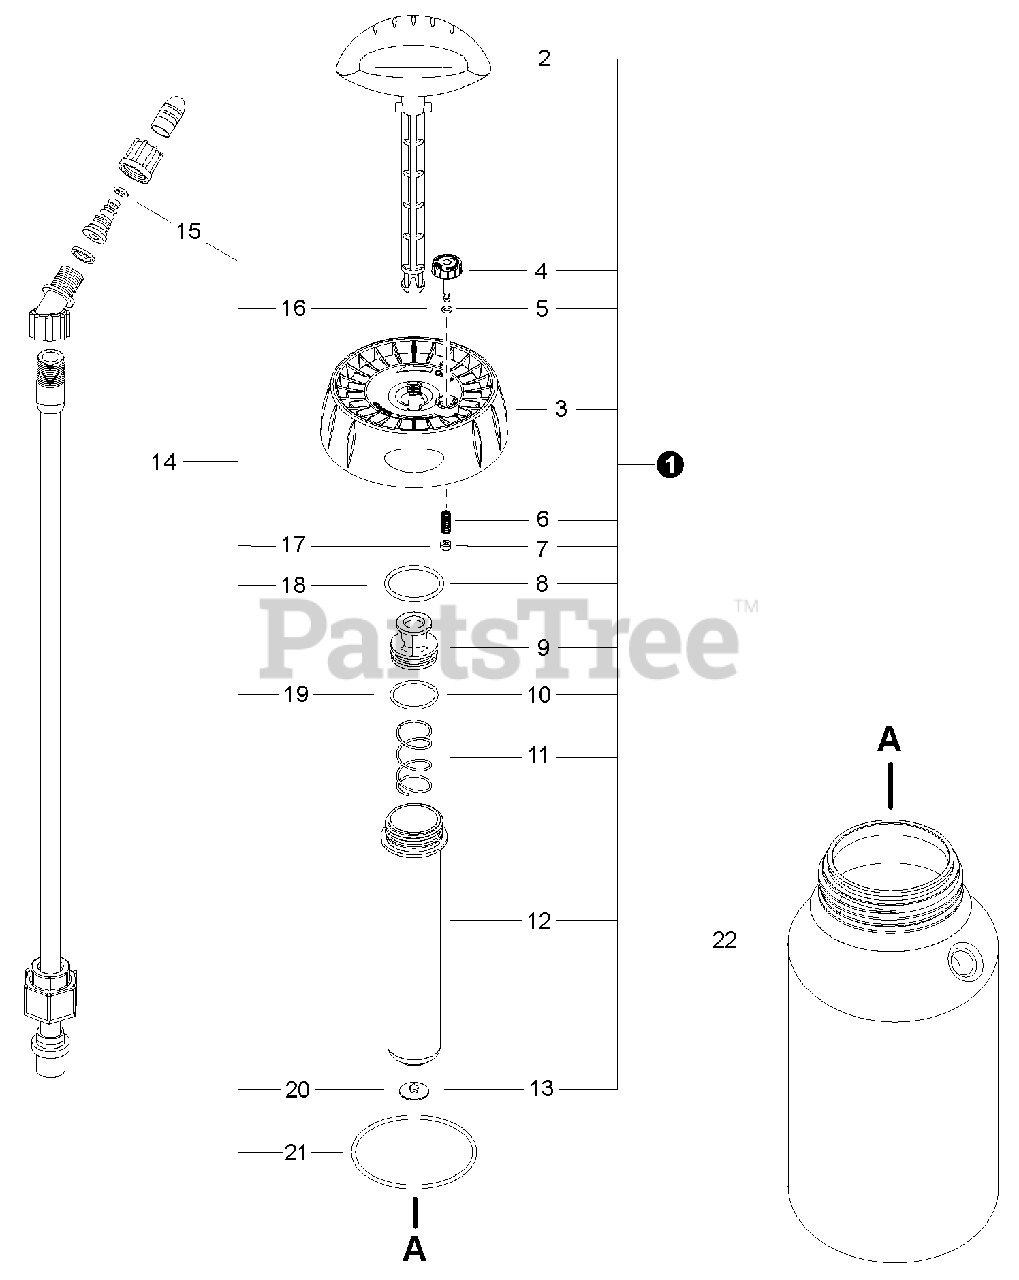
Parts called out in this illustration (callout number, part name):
1	PUMP ASSY
2	HANDLE, PUMP
3	CAP, TANK
4	CAP
5	O-RING, PRV
6	SPRING, PRV
7	RING, RETAINING - PRV
8	O-RING, BARREL
9	PLUNGER, PUMP
10	O-RING, PLUNGER
11	SPRING, PUMP
12	BARREL, PUMP
13	VALVE, CHECK
14	PUMP REPAIR KIT
15	O-RING, NOZZLE
16	O-RING, PRV
17	RING, RETAINING - PRV
18	O-RING, BARREL
19	O-RING, PLUNGER
20	VALVE, CHECK
21	O-RING
22	TANK, SPRAYER
